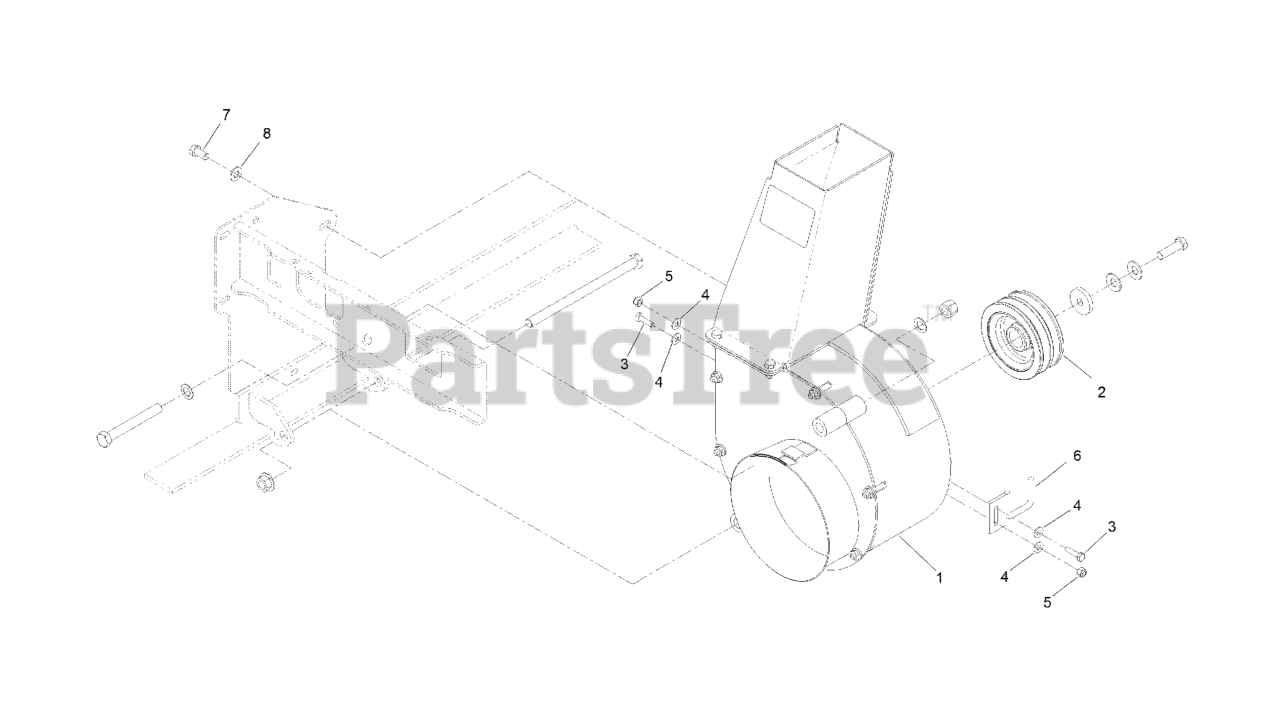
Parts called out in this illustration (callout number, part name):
1	BLOWER ASM
3	SCREW-HH
4	WASHER-FLAT
5	NUT-LOCK, NI
7	SCREW-HH
8	WASHER-FLAT
